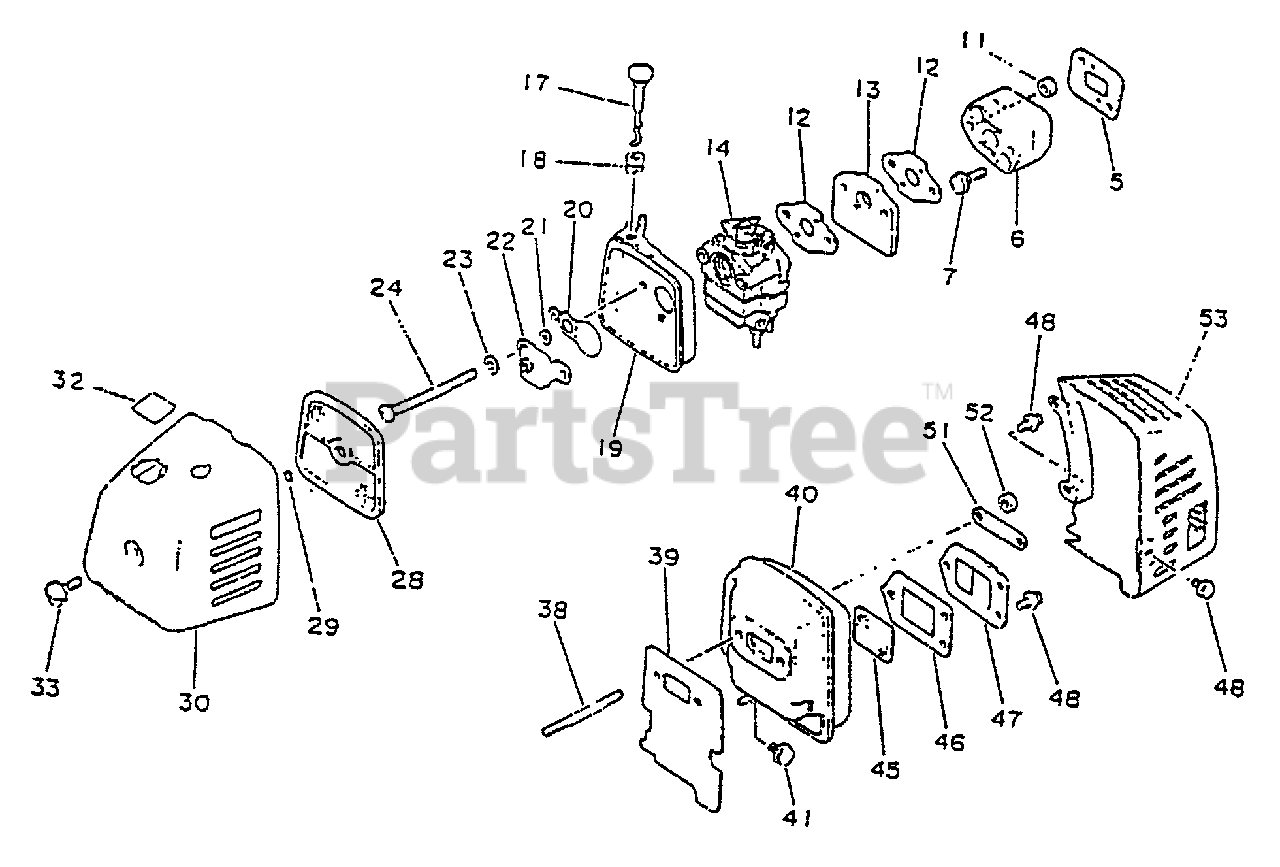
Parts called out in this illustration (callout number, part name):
5	GASKET, INTAKE
6	INSULATOR, INTAKE
7	SCREW - 5X20
12	GASKET, INTAKE
13	INSULATOR
14	CARBURETOR WY-18
17	ROD, CHOKE
19	CASE, AIR FILTER
20	SHUTTER, CHOKE
21	WASHER - 5
22	PLATE, PREVENT
23	LOCKWASHER - 5
24	SCREW - 5X60
28	FILTER, AIR
29	O-RING - 4
30	AIR FILTER COVER ASSY
32	LABEL - CHOKE
39	GASKET, EXHAUST
41	SCREW - 5X10
45	SCREEN, SPARK ARRESTOR
46	GASKET, EXHAUST
47	GUIDE, EXHAUST
48	SCREW - 4X10
52	LOCKNUT - 5
53	COVER, EXHAUST
